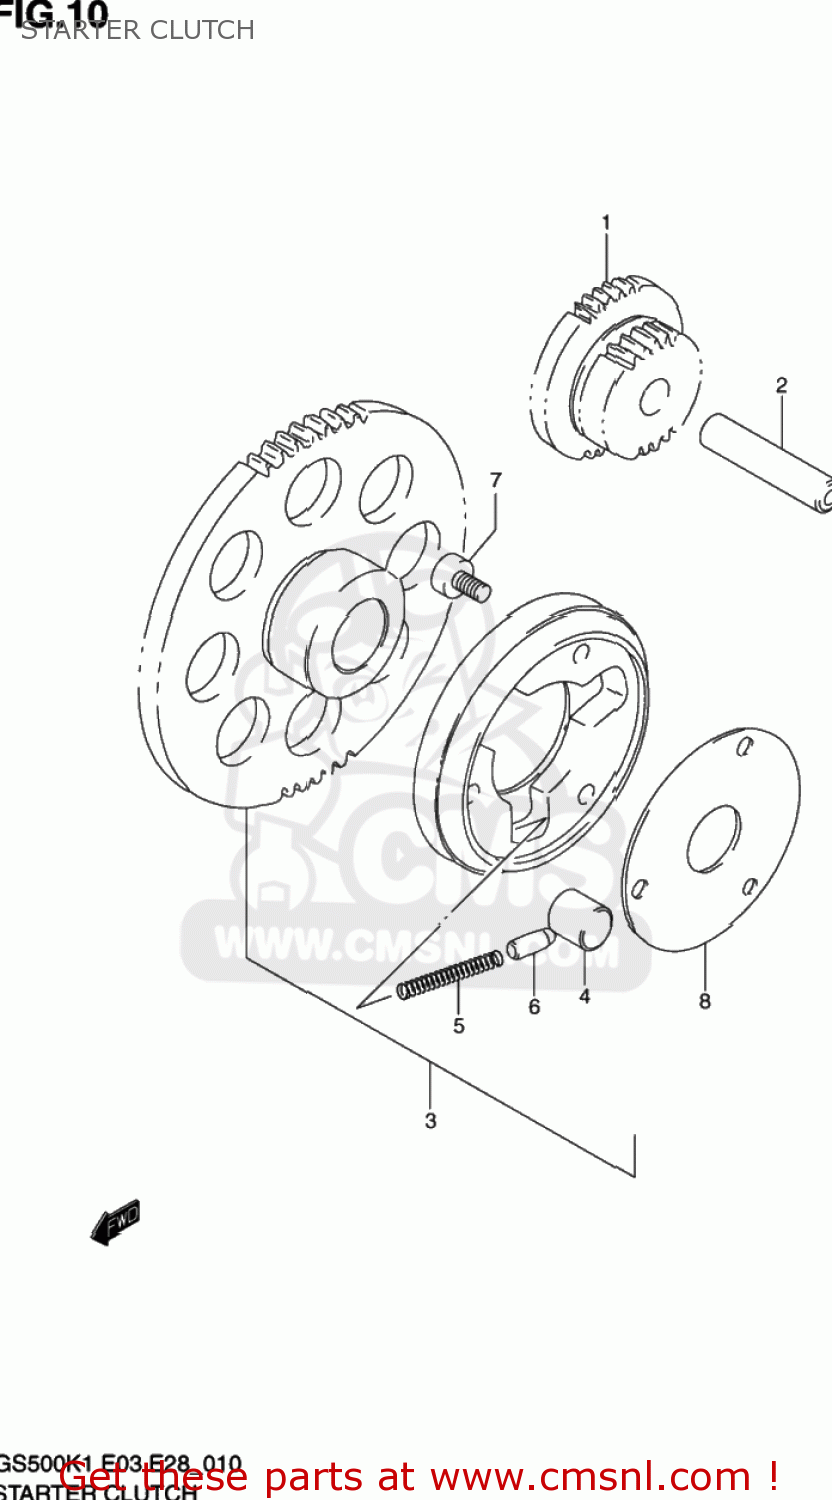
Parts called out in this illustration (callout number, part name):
1	GEAR,STARTER IDLE
2	PIN(7.4X13X56)
3	CLUTCH SET,STARTER
4	ROLLER(15X13)
5	SPRING
6	PIECE,PUSH
7	BOLT
8	SHIM,STARTER CLUTCH HUB
